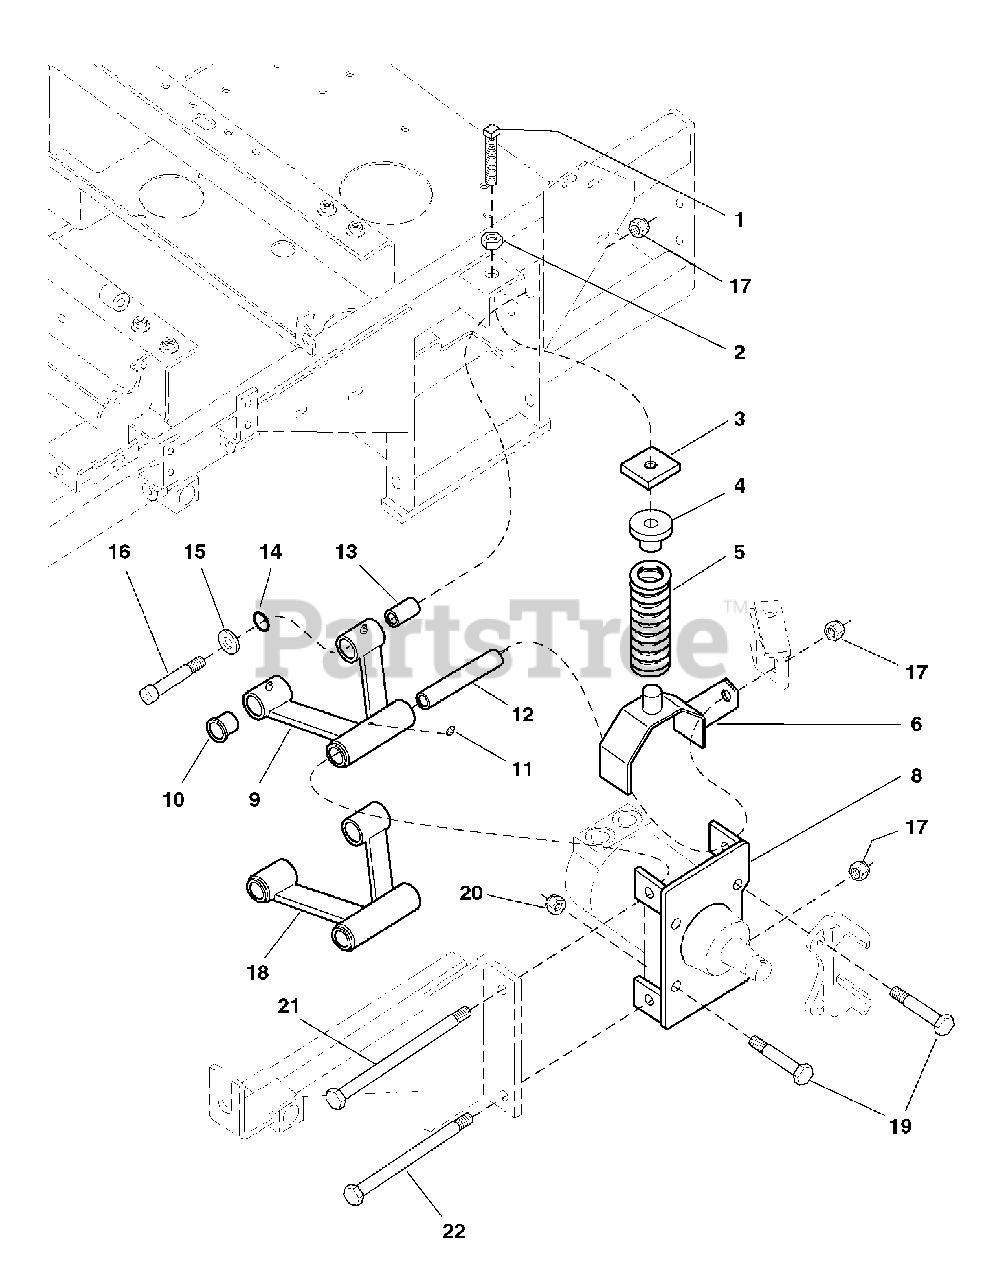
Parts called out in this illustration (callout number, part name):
1	SET SCREW, Square Hd, 1/2-13 x 3
2	NUT, Hex, Jam, 1/2-13
3	SPRING COMPRESSION PLATE
4	SPRING RETAINER
5	SPRING, Suspension
6	SPRING SADDLE-LH
8	WHEEL MOTOR MOUNT
9	SUSPENSION A-ARM, Upper
10	BUSHING, Flange
11	GREASE FITTING
12	PIVOT SLEEVE, Long
13	PIVOT SLEEVE, Short
15	WASHER, A-Arm
16	CAPSCREW, Allen Head, 1/2-13 x 3
17	NUT, Hex, Nylon Lock, 1/2-13
18	SUSPENSION A-ARM, Lower
19	CAPSCREW, Hex Hd, 1/2-20 x 3
20	NUT, Hex, Nylon Lock, 1/2-20
21	CAPSCREW, Hex Hd, 1/2-13 x 7-1/2
22	CAPSCREW, Hex Hd, 1/2-13 x 6-1/2
